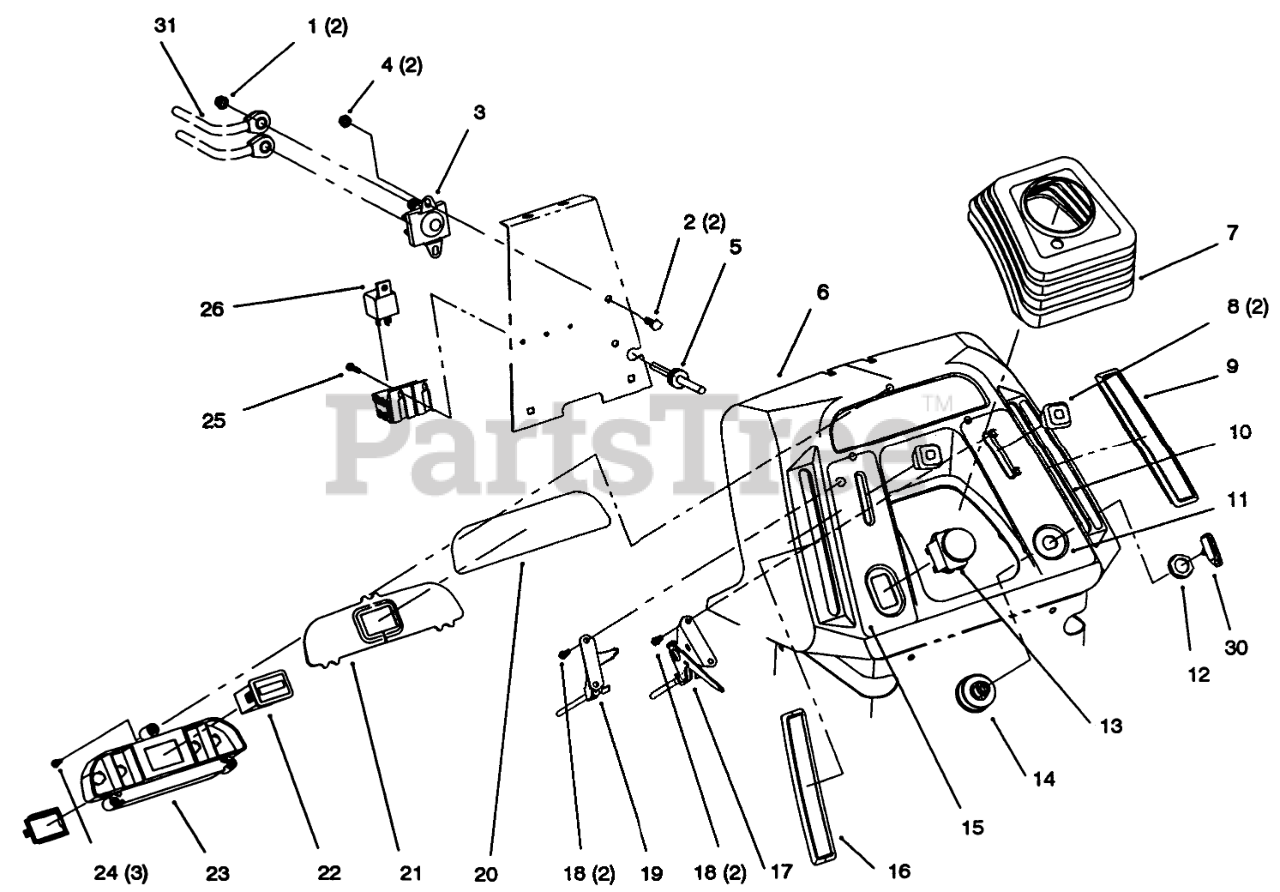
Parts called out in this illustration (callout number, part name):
1	Nut-Hex (Only On: 72043, 72042, 72063, 72062)
2	Screw-HH (Only On: 72043, 72042, 72063, 72062)
3	Solenoid-12 Volt (Only On: 72043, 72042, 72063, 72062)
4	Nut-Hex Lock (Only On: 72043, 72042, 72063, 72062)
5	GROMMET-RUBBER
6	DASH
7	BOOT-STEERING
9	Cover-Slot RH (Only On: 72043, 72063, 72083, 72103)
10	Decal-Shift (Only On: 72042, 72062)
11	Decal-Throttle/Ignition (Only On: 72042, 72043, 72083)
11	Decal-Throttle/Ignition (Only On: 72103, 72063, 72062)
13	Switch-PTO
14	SWITCH-IGNITION
15	Decal-Choke/PTO (Only On: 72042, 72043, 72083)
15	Decal-PTO/Choke (Only On: 72103, 72063, 72062)
16	COVER-SLOT, LH
17	Control-Throttle (Only On: 72043, 72042, 72063, 72062)
17	Control-Throttle (Only On: 72103, 72083)
19	Control-Choke (Only On: 72043, 72042, 72063, 72062)
19	Control-Choke (Only On: 72103, 72083)
20	Decal-Dash Lens (Only On: 72043, 72083, 72103)
20	Decal-Dash Lens (Only On: 72042, 72062, 72063)
21	LENS-DASH
22	Hourmeter
23	Light-Indicator (Only On: 72043, 72083, 72103)
23	Housing-Indicator Light (Only On: 72042, 72062, 72063)
24	SCREW-PPH
25	SCREW-PPHTF
26	RELAY
30	KEY-IGNITION
31	Cable-Battery Red (Only On: 72043, 72042, 72063, 72062)
